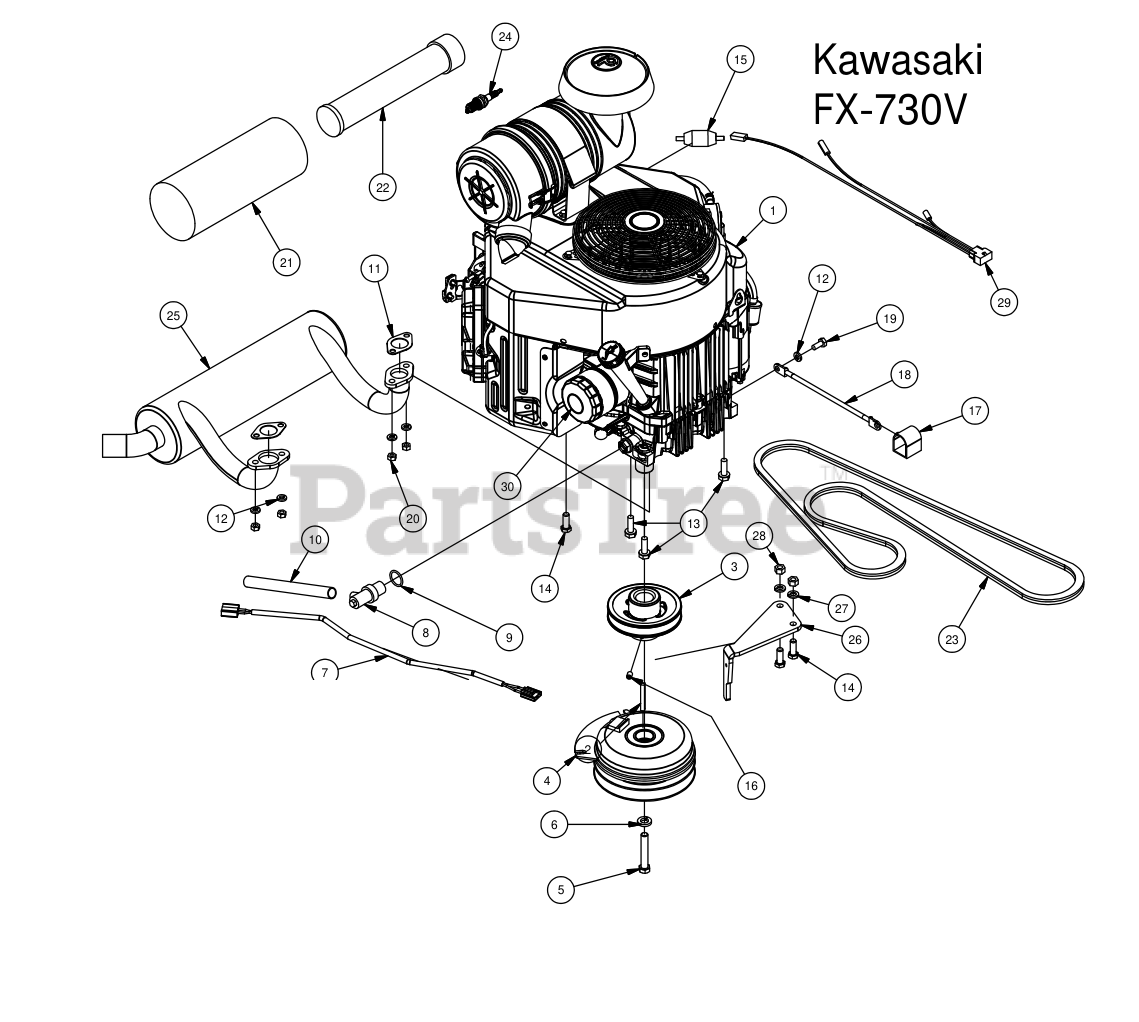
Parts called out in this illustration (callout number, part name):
2	1/4 x 2 Square key Stock
3	4 3/4 Motor Pulley
4	Clutch Assembly
5	7/16" x 2 1/2" Hex Bolt
6	7/16" Lock Washer
7	Clutch Pigtail
10	1/2 Clear Braded Hose Priced/Foot
11	Exhaust Gasket
12	5/16" Lock Washer
13	3/8 x 1 1/8 bolt
14	3/8" x 1" Hex Bolt
15	Universal Inline Fuel Filter
16	5/16 Set Screw
17	Black Boot For Ground Cable
18	Ground Cable
19	M8x1.20x20MM Hex head bolt
20	M8-1.25 Zinc Nut
21	Canister Air Filter- Outer
22	Canister Air Filter- Inner
24	Spark Plug - Kawasaki
25	Exhaust Kawasaki
26	PTO Engager Holder
27	3/8" Lock Washer
28	3/8-16 Hex Nuts Zinc
29	Harness Adaptor
30	Kawasaki Oil Filter
